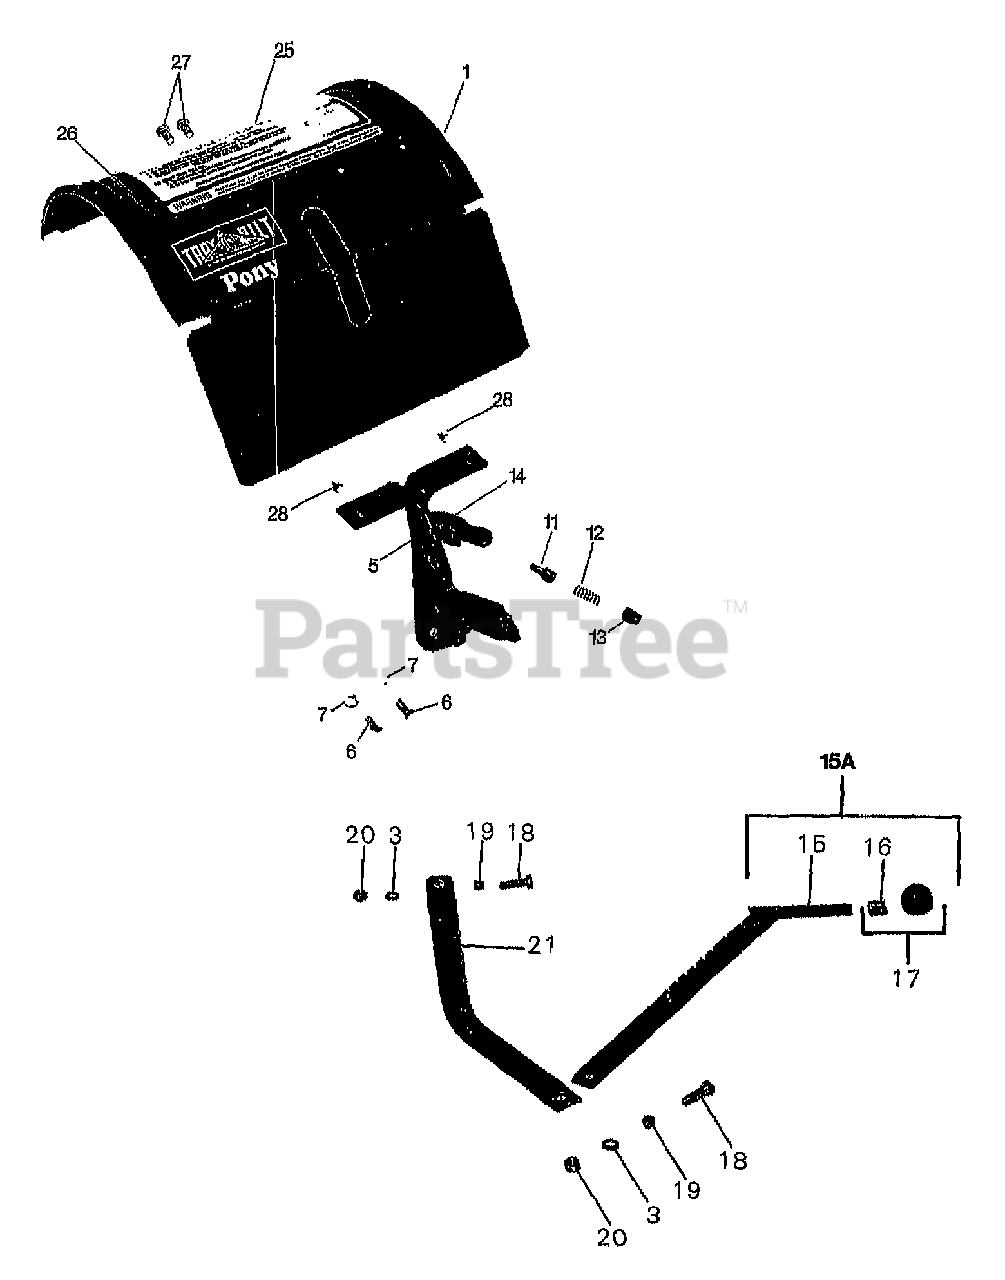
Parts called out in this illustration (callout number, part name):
1	HOOD W/DECALS #20733 & 20401
3	WASHER-LK .375 @ DEPL
5	KIT-REAR HOOD BRKT (INCL. ROLL PIN #9308)
6	SCR-HHC 5/16-18X.75 GR 5 ZP (BRACKET TO REAR BEARING CAP)
7	WASHER-LK .312 ZP
11	PLUNGER
12	SPRING .406 X 1.25
13	PLUG-PIPE 1/4 NPT
14	PIN-ROLL .25 X 1
15	BAR (NOT AVAILABLE SEP.)
15A	DEPTH REGULATOR W/KNOB (INCL. 15-17)
16	RING-TOLERANCE .5325 ID
17	KNOB-CONTROL
18	SCR-HH 3/8-16X1.25
19	BUSHING-.5X.375X.3
20	NUT-HEX 3/8-16 ZP
21	DRAG BAR-BENT
25	DECAL-OPER INST
26	DECAL-HOOD LOGO PONY OPC
27	SCR-HWH 5/16-18 X .5 STH
28	SCR-HWH 1/4-20 X .5 STH (ATTACHES HOOD TO DEPTH REGULATOR BRACKET)
